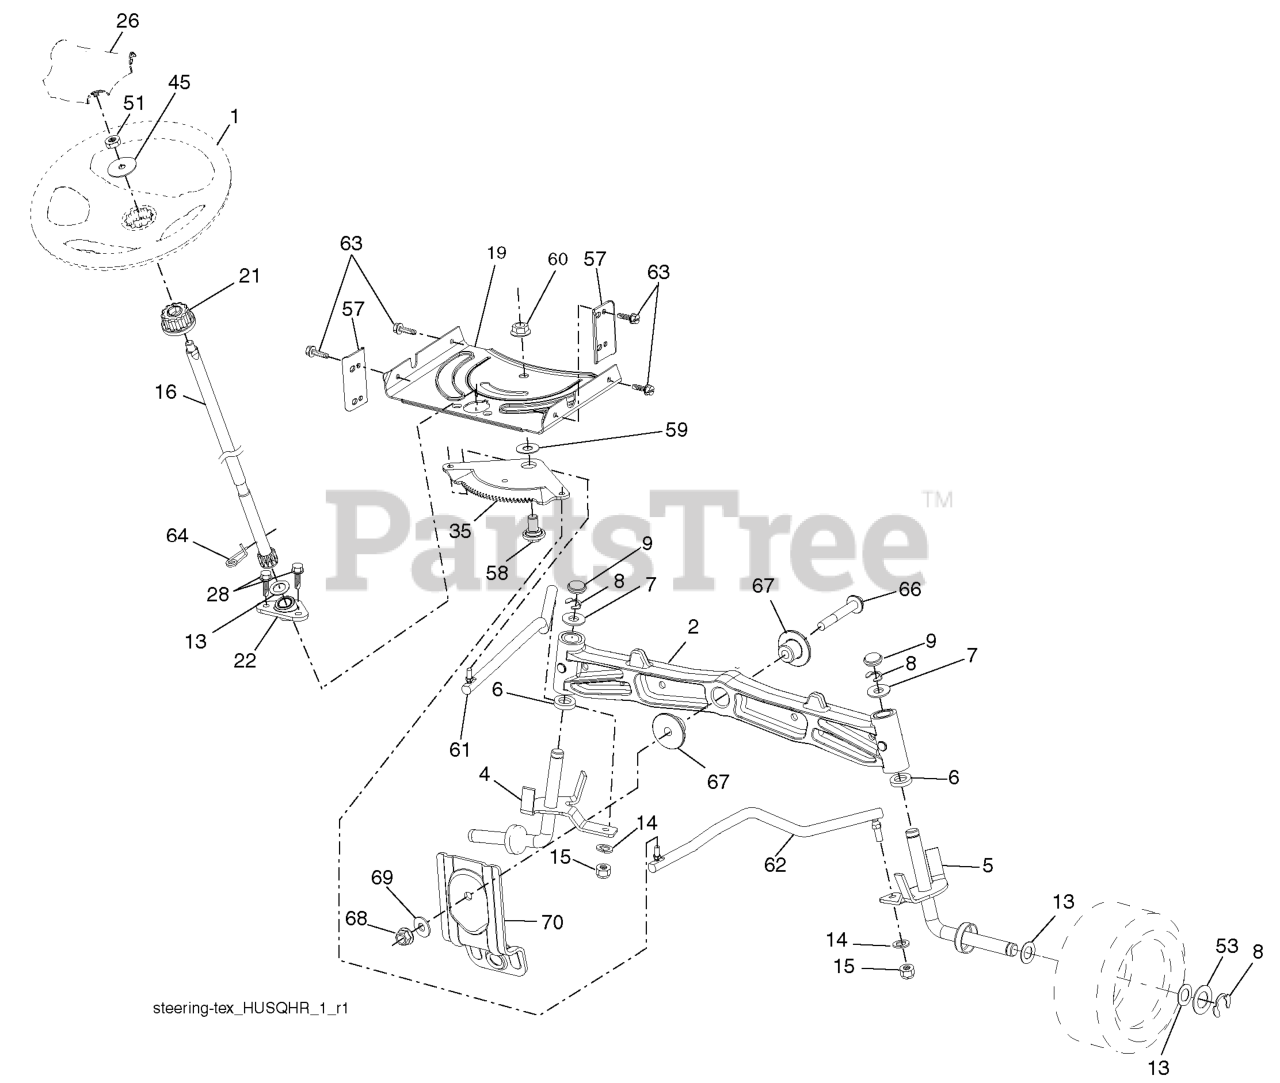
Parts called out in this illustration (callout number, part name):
1	RP WHEEL.STEER.HUSQ.PREM.OVMLD
2	AXLE.CAST.IRON
4	SPINDLE.WELDED.LH.15"TEX
5	SPINDLE.WELDED.RH.15"T
6	THRUST WASHER
9	CAP.SPINDLE.BLACK
14	WASHER, LOCK 3/8
15	NUT CROWNLOCK 3/8-24
16	SHAFT, STEERING
19	PLATE.STEER.DDL.NLT/NG
21	ADAPTER, WHEEL STNG..
22	STEERING.SUPT.LOWER.
26	RP INSERT.CAP.WHL.STRG.HUSQ.
28	SCREW, 3/8-16X3/4
35	GEAR.SECTOR.PLATE.DDL.
45	WASHER 9/16"ID, 2 3/8"OD
51	NUT.HEX.1/2-20
53	WASHER.HARDENED
57	BRACKET.UPSTOP.TEX
58	BOLT.SHOULDER.SECTOR.P
59	WASHER.THURST.SECTOR.S
60	NUT FLANGE LOCK 5/8-11
61	DRAGLINK.LH.BALLSTUD.D
62	DRAGLINK.RH.BALLSTUD.D
63	SCREW
64	RETAINER.CLIP.SPRING.S
66	BOLT HEX FGHD 7/16-14 X 3 SERR
67	BUSHING.PM.FRONT AXLE
68	NUT.LOCK.FLANGE.7/16
69	WASHER.1.5X.505X.118
70	BRKT.DECK.SUSPENSION.F
